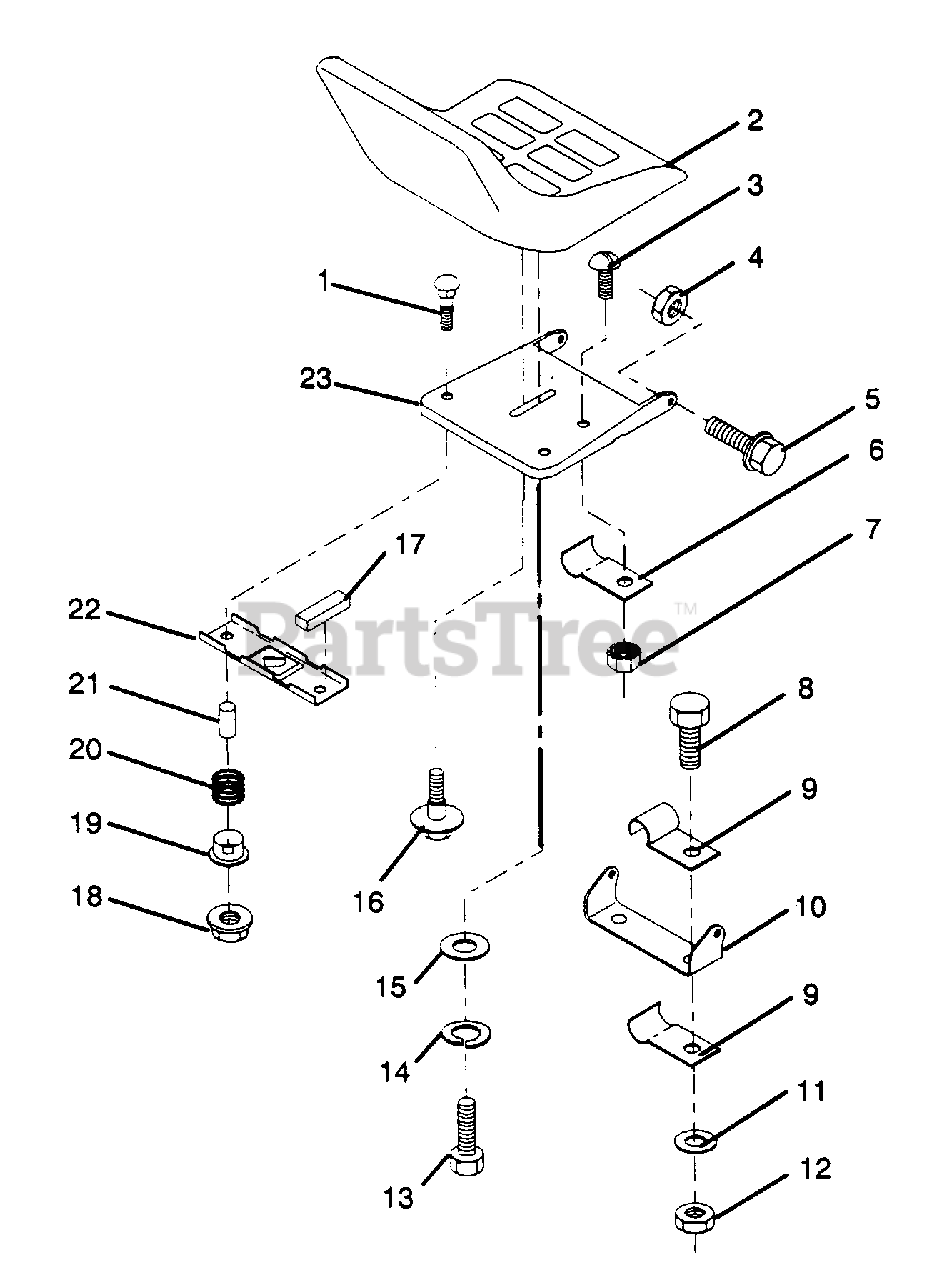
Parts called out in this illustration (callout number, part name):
1	Bolt, Carriage 1/4-20 x 1 1/4 (AYP part number)
2	Seat (AYP part number)
3	Screw, Slotted Pan Head 10-32 x 1/2 (AYP part number)
4	Nut, Crownlock 5/16-18
5	Bolt, Shoulder 5/16-18 UNC (AYP part number)
6	Clip, Insulated (AYP part number)
7	Nut, Keps 10-32 UNF (AYP part number)
8	Bolt, Fin. Hex 3/8-16 UNC x 3/4 (AYP part number)
9	Clip, Insulated (AYP part number)
10	Bracket, Pivot Seat (AYP part number)
11	Washer 13/32 x 3/4 x 10 Ga. (AYP part number)
12	Nut, Crownlock 3/8-16 UNC
13	Bolt, Fin Hex 1/2-13 UNCx 7/8 Gr. 5 (AYP part number)
14	Washer, Lock Hvy Helical Spring (AYP part number)
15	Washer, 17/32 x 1 3/16 x 12 Ga. (AYP part number)
16	Bolt, Shoulder (AYP part number)
17	Strip, Foam (AYP part number)
18	Nut, Hex Large Flange Loc. (AYP part number)
19	Bushing, Snap (AYP part number)
20	Spring, Compression (AYP part number)
21	Spacer, Split 28 Id. x .88 Lg. (AYP part number)
22	Bracket, Switch, Mounting (AYP part number)
23	Pan, Seat (AYP part number)
